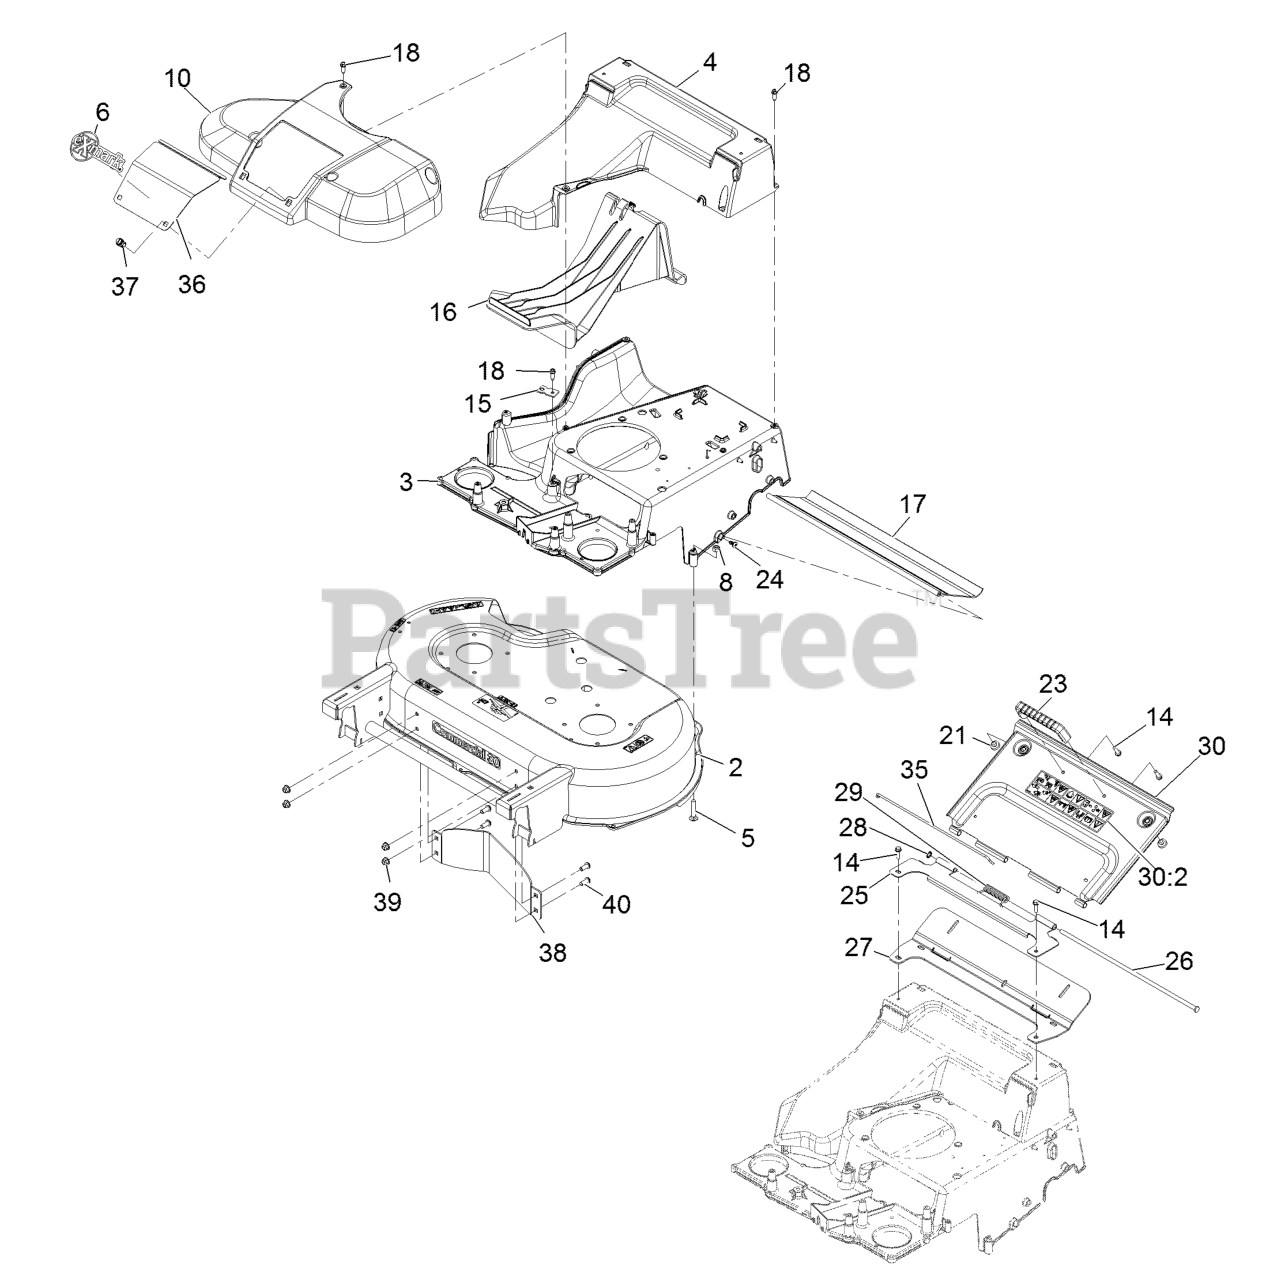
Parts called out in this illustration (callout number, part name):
5	BOLT-CAR
8	NUT-LOCK, NI
10	COVER-BELT
14	SCREW-HWH
16	PLUG-MULCH
17	SHIELD-TRAILING
18	SCREW-HWHTF
23	HANDLE-DOOR
24	SCREW-PTH
25	BRACKET-HINGE
26	PIN-HINGE
27	SEAL-DOOR
28	RING-RETAINING
29	SPRING-TORSION, COVER
30	REAR DOOR ASM
30:2	DECAL-WARNING
35	CLIP-SEAL
36	DOOR-ACCESS
37	FASTENER
39	NUT-HF, NI
40	SCREW-HSBH
